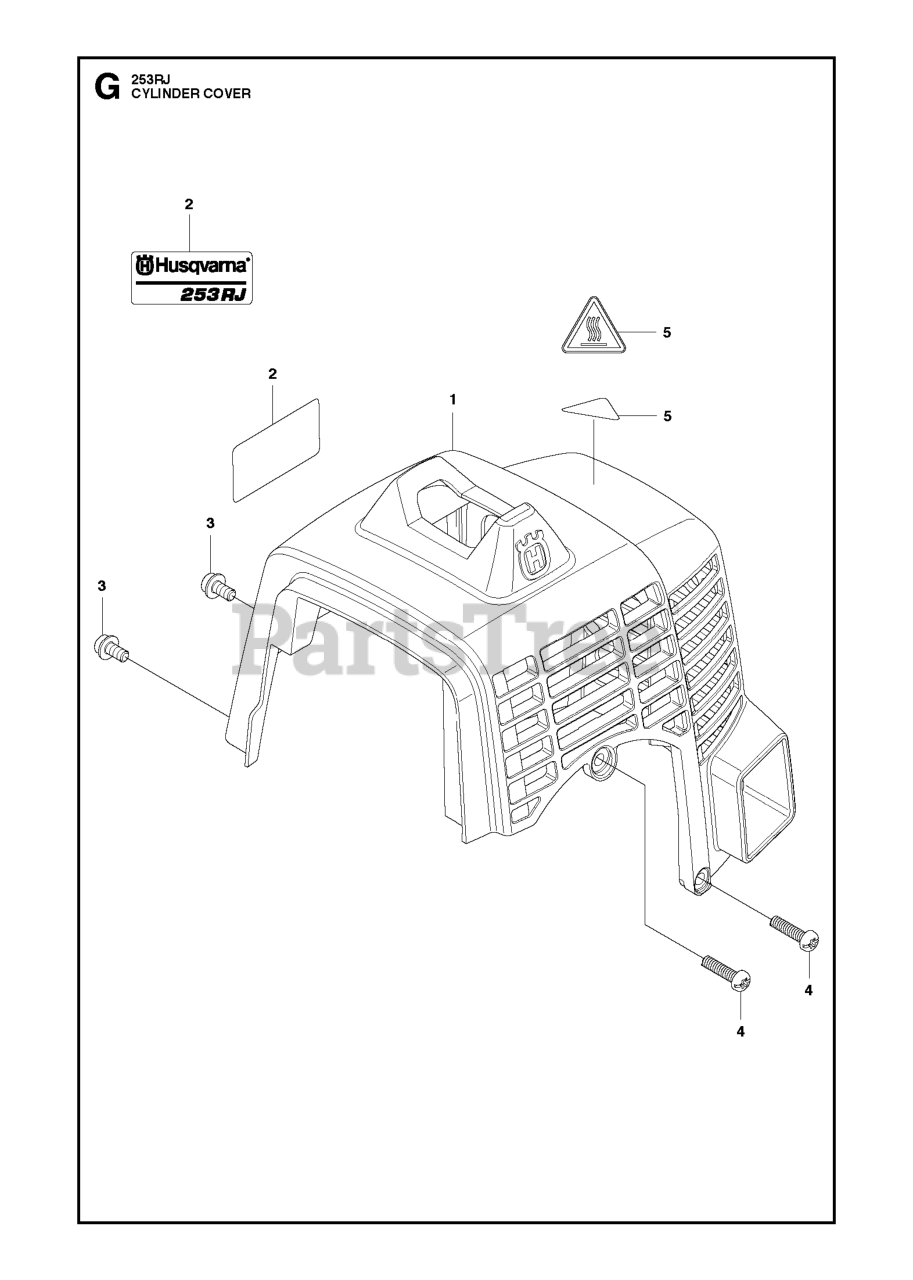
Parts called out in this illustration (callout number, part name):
3	BOLT (RPLS T495051010-11)
4	SCREW, TORX (RPLS T4970-52001)
5	LABEL HOT CAUTION
